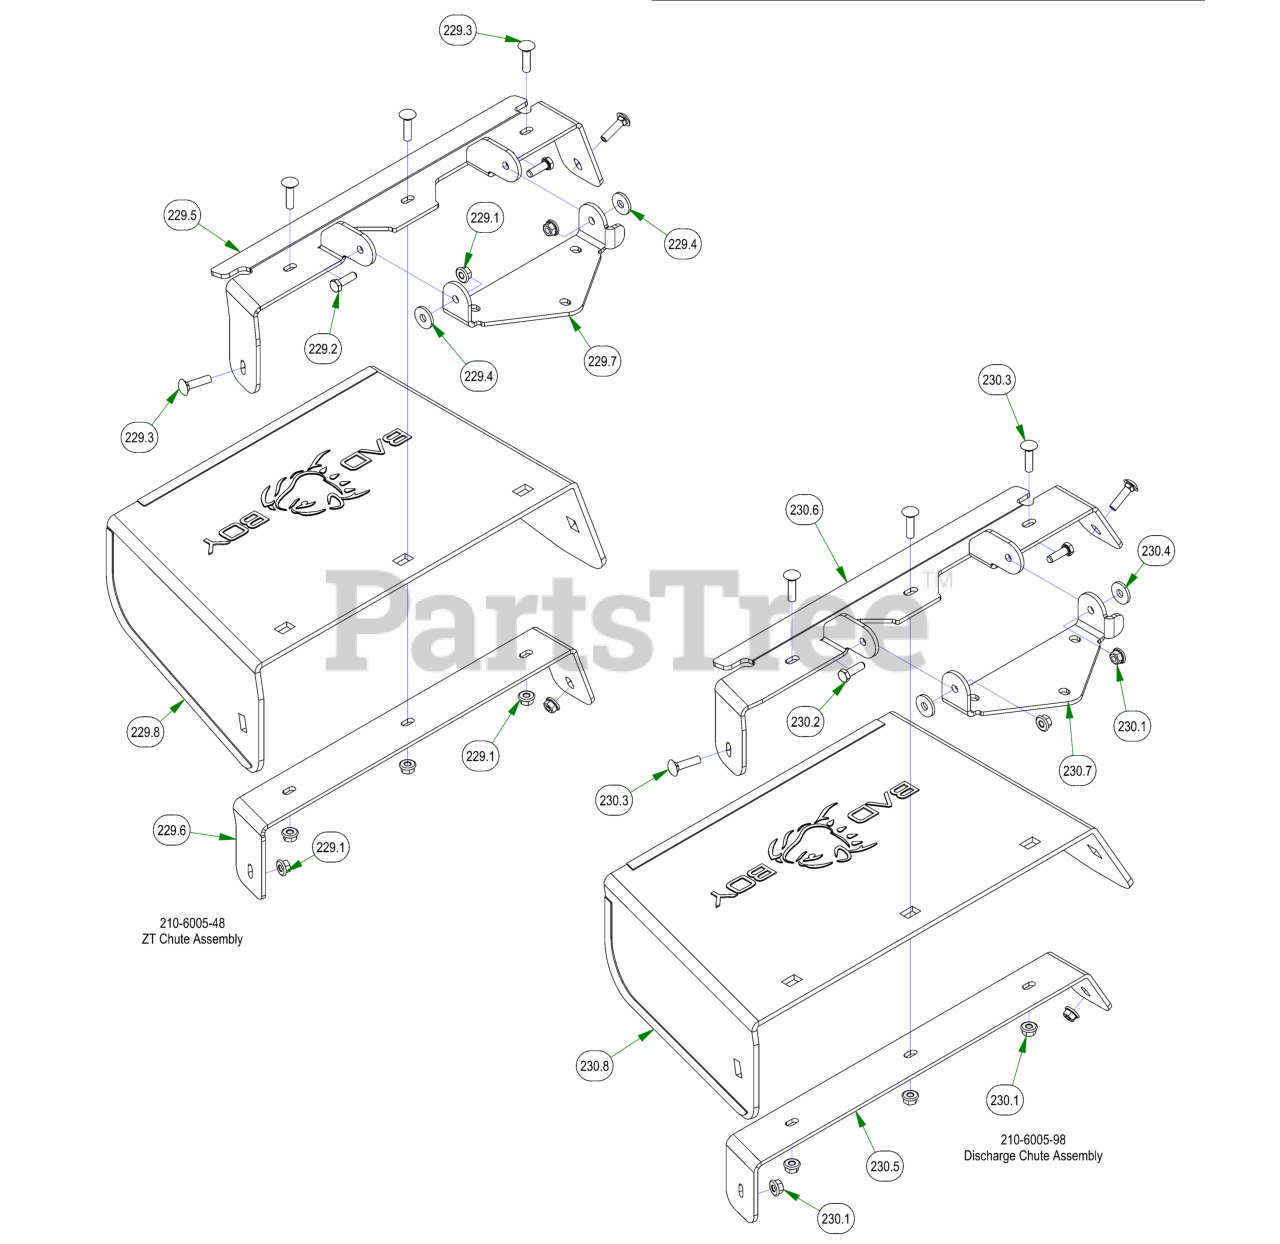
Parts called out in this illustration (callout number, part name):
229	ZT Chute Assembly
229.1	5/16-18 NYLON INSERT FLANGE LOCKNUT ZINC
229.2	5/16-18 X 1 HEX CAP SCREW (GR.5) ZINC
229.3	5/16-18 X 1-1/4 CARRIAGE BOLT ZINC
229.4	.360 ID X .983 OD X .120 THICK FLAT WASHER NYLON
229.5	Discharge Upper Chute Bracket
229.6	Discharge Lower Chute Bracket
229.7	Discharge Chute Hanger (deck mounted)
229.8	Rubber Discharge Chute
230	Discharge Chute Assembly
230.1	5/16-18 NYLON INSERT FLANGE LOCKNUT ZINC
230.2	5/16-18 X 1 HEX CAP SCREW (GR.5) ZINC
230.3	5/16-18 X 1-1/4 CARRIAGE BOLT ZINC
230.4	.360 ID X .983 OD X .120 THICK FLAT WASHER NYLON
230.5	60" Discharge Lower Bracket
230.6	60" Discharge Chute Upper Hanger
230.7	Discharge Chute Hanger (deck mounted)
230.8	Rubber Discharge Chute
